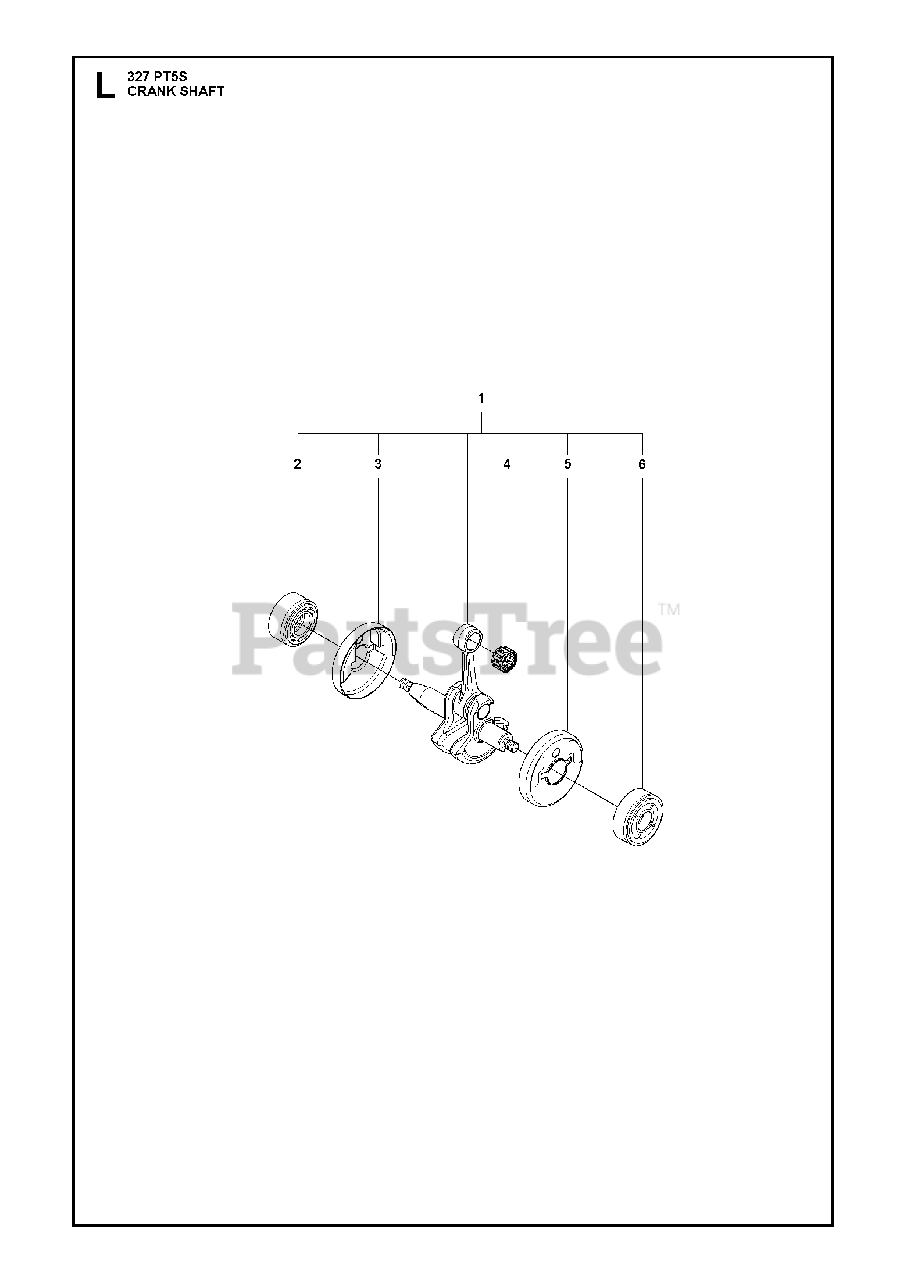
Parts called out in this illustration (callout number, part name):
1	CRANKSHAFT
2	BEARING CAP
3	CUP
4	BEARING
5	CUP
6	BEARING CAP
